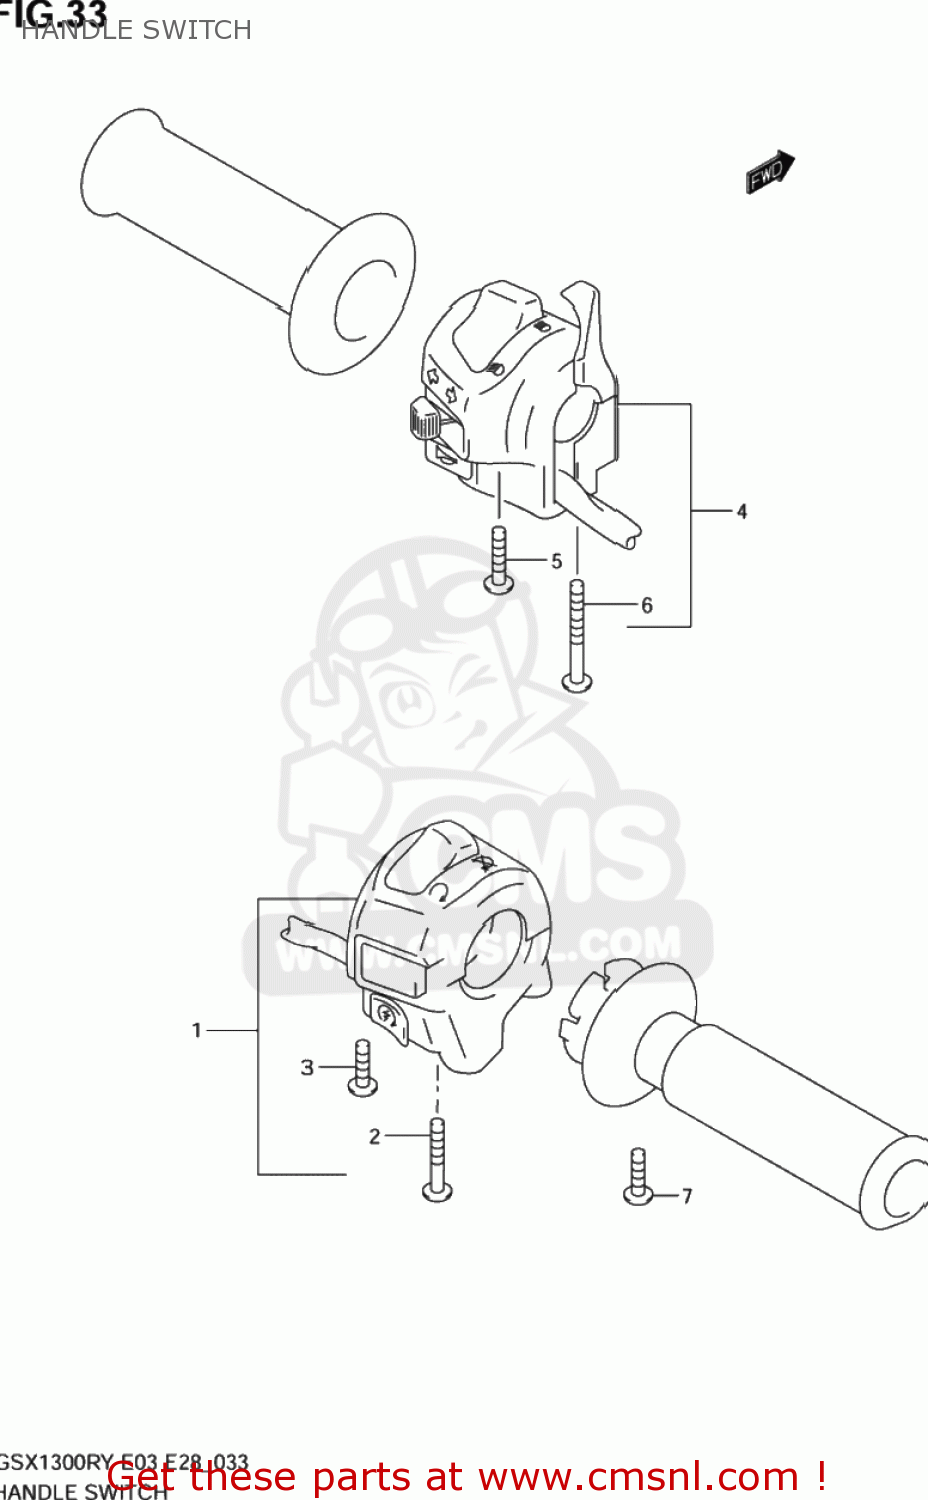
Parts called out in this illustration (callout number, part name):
1	SWITCH ASSY,HANDLE,R
2	SCREW
3	SCREW
4	SWITCH ASSY,HANDLE,L
5	SCREW
6	SCREW, 5X45
7	SCREW
